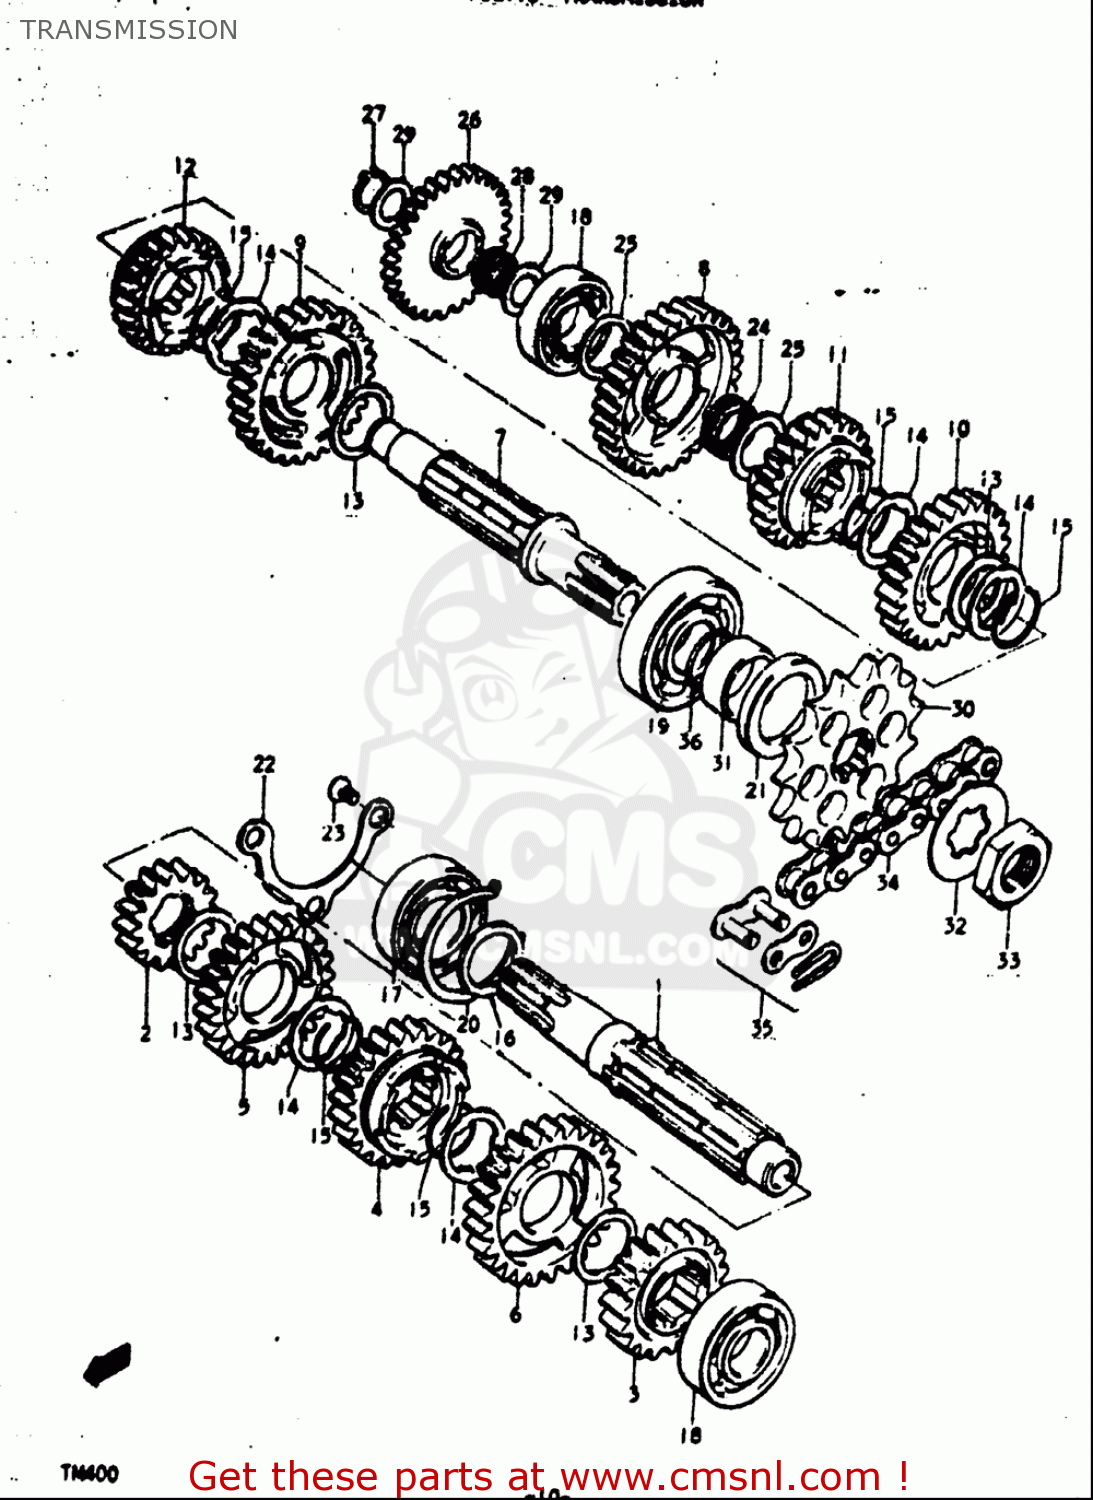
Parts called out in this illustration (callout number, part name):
13	WASHER
14	WASHER,LOCK
15	RING,SNAP
17	BEARING
18	BEARING(20X47X14)
19	BEARING(22X56X16)
21	SEAL,OIL(32X42X6)
22	RETAINER,BEARING
23	SCREW
25	WASHER (20X30X1)
27	CIRCLIP
28	BEARING(17X21X9.8)
29	WASHER
30	SPROCKET,ENGINE
32	WASHER,LOCK
33	NUT
34	CHAIN,DRIVE #525TR-10
35	JOINT ASSEMBLY,CHAIN
36	O RING(D:1.7,ID:22)
